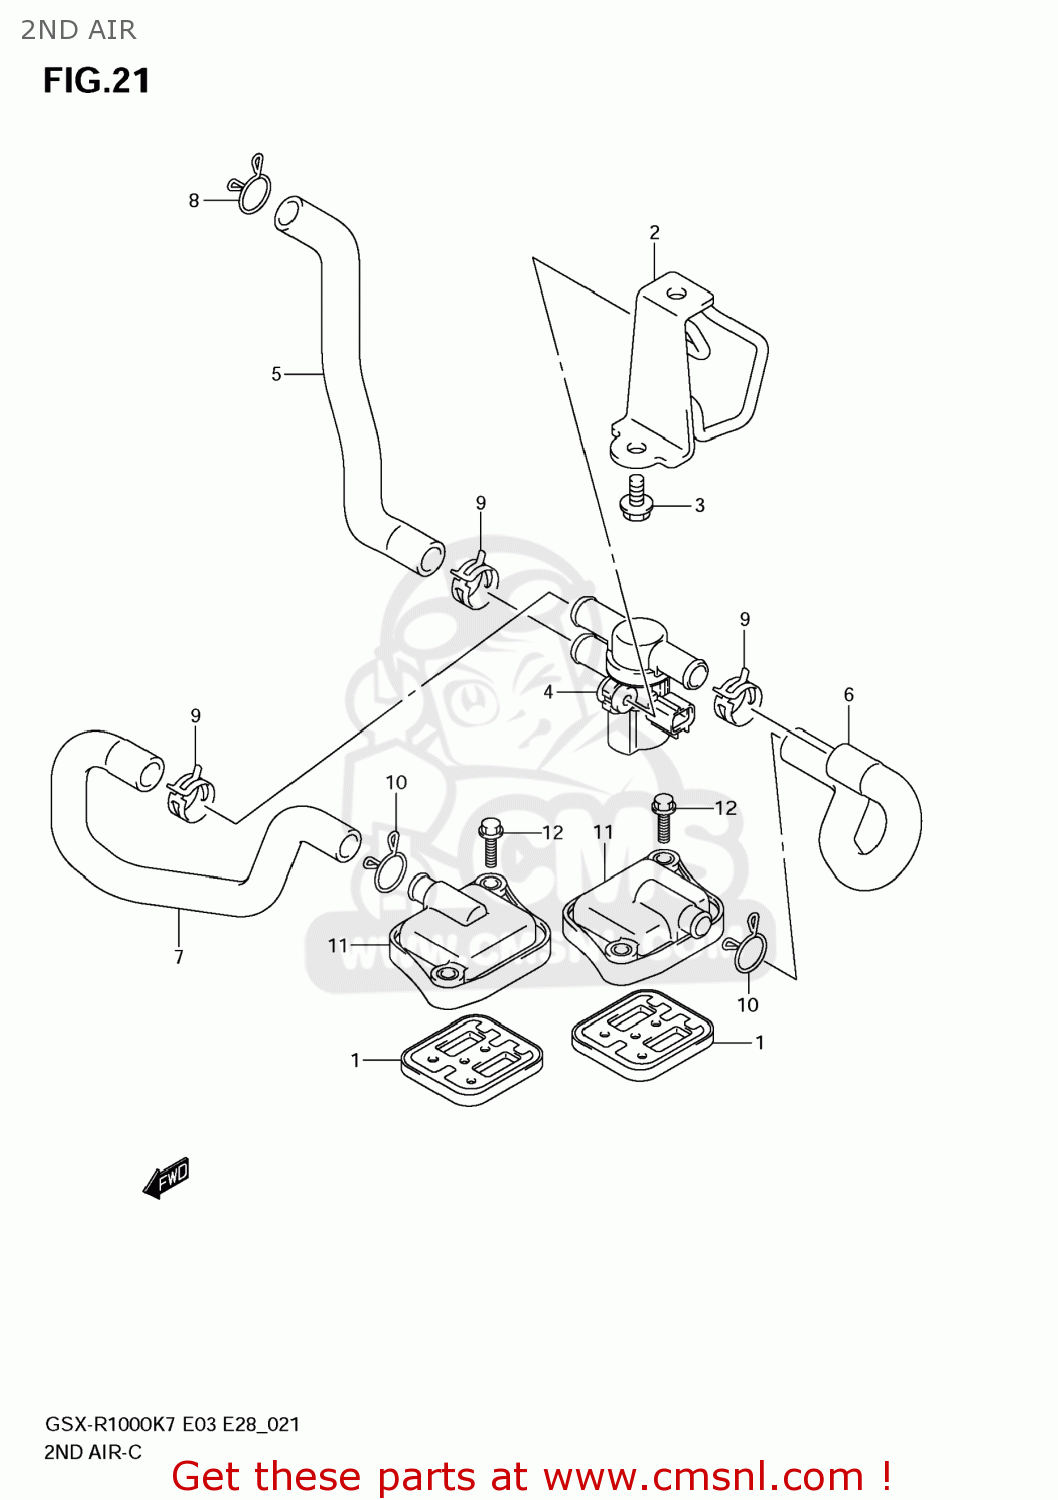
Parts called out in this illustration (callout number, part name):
1	VALVE ASSY,2ND AIR REED
2	BRACKET,2ND AIR VALVE
3	BOLT
4	VALVE ASSY,AIR CUT
5	HOSE,2ND AIR CLEANER
6	HOSE,AIR CUT VALVE,L
7	HOSE,AIR CUT VALVE,R
8	CLIP
9	CLIP
10	CLAMP
11	COVER,2ND AIR REED VALVE
12	BOLT(6X20)
